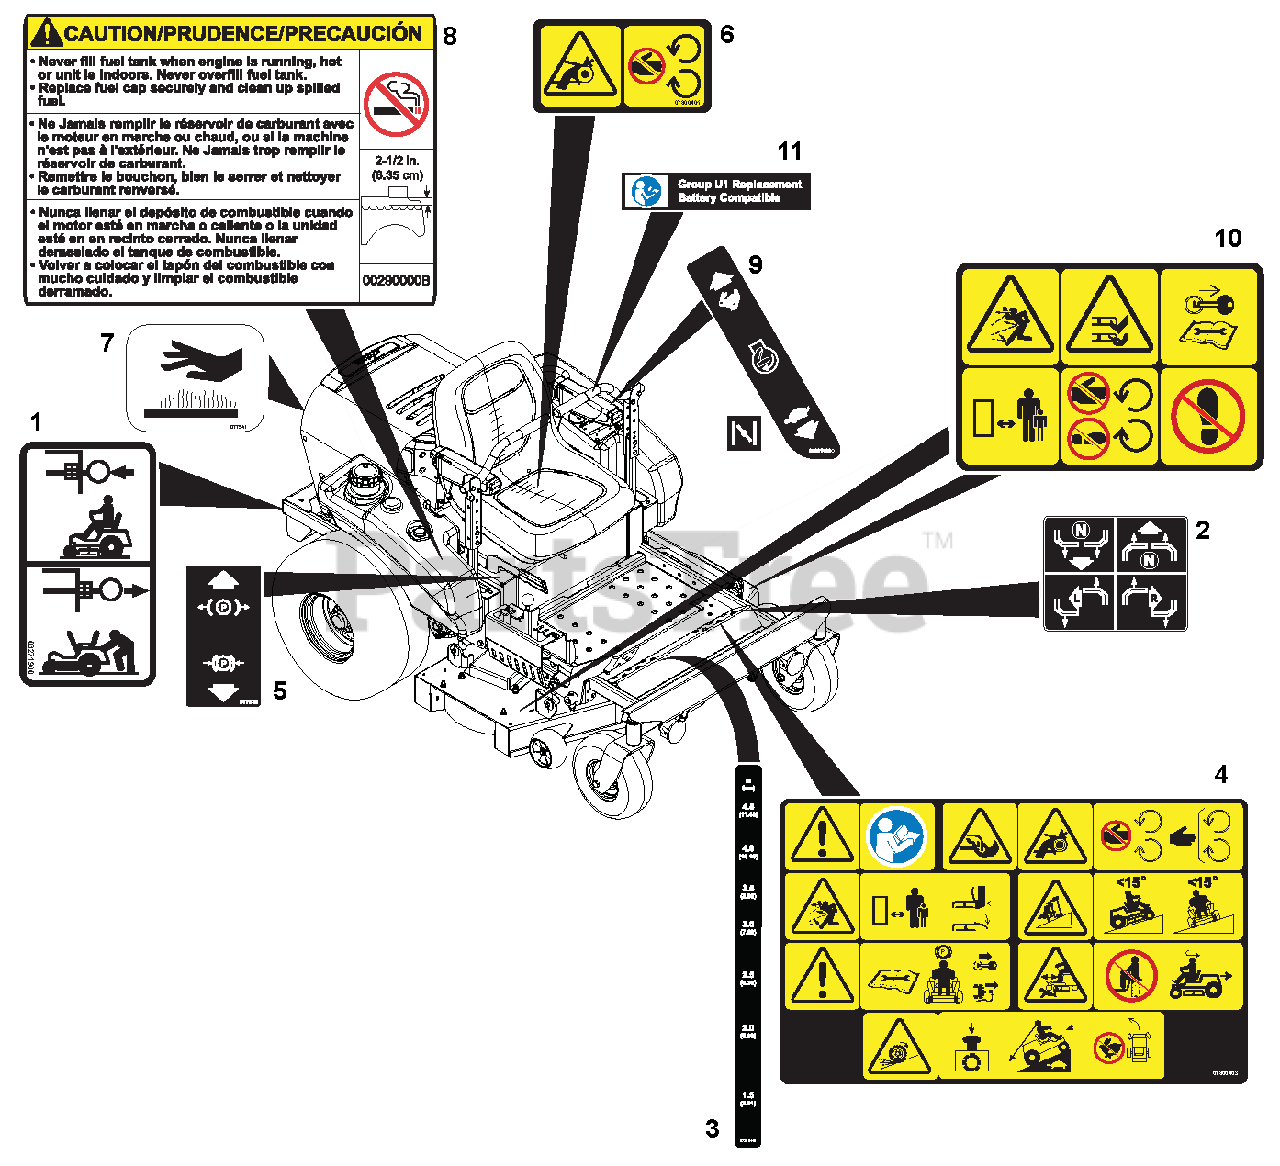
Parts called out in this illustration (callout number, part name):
1	DECAL, TRANSMISSION DISCONNECT
2	DECAL, INSTRUCTIONAL-STEERING
3	DECAL, CUT HEIGHT XL
4	DECAL, MAIN SAFETY
5	DECAL, PARKING BRAKE LEVER
6	DECAL, SAFETY - GUARDING
7	DECAL, HOT SURFACE
8	DECAL,FUEL WARNING
9	DECAL, SPEED CONTROL
10	DECAL, SAFETY - MOWER DECK
11	DECAL, U1 BATTERY REPLACEMENT
